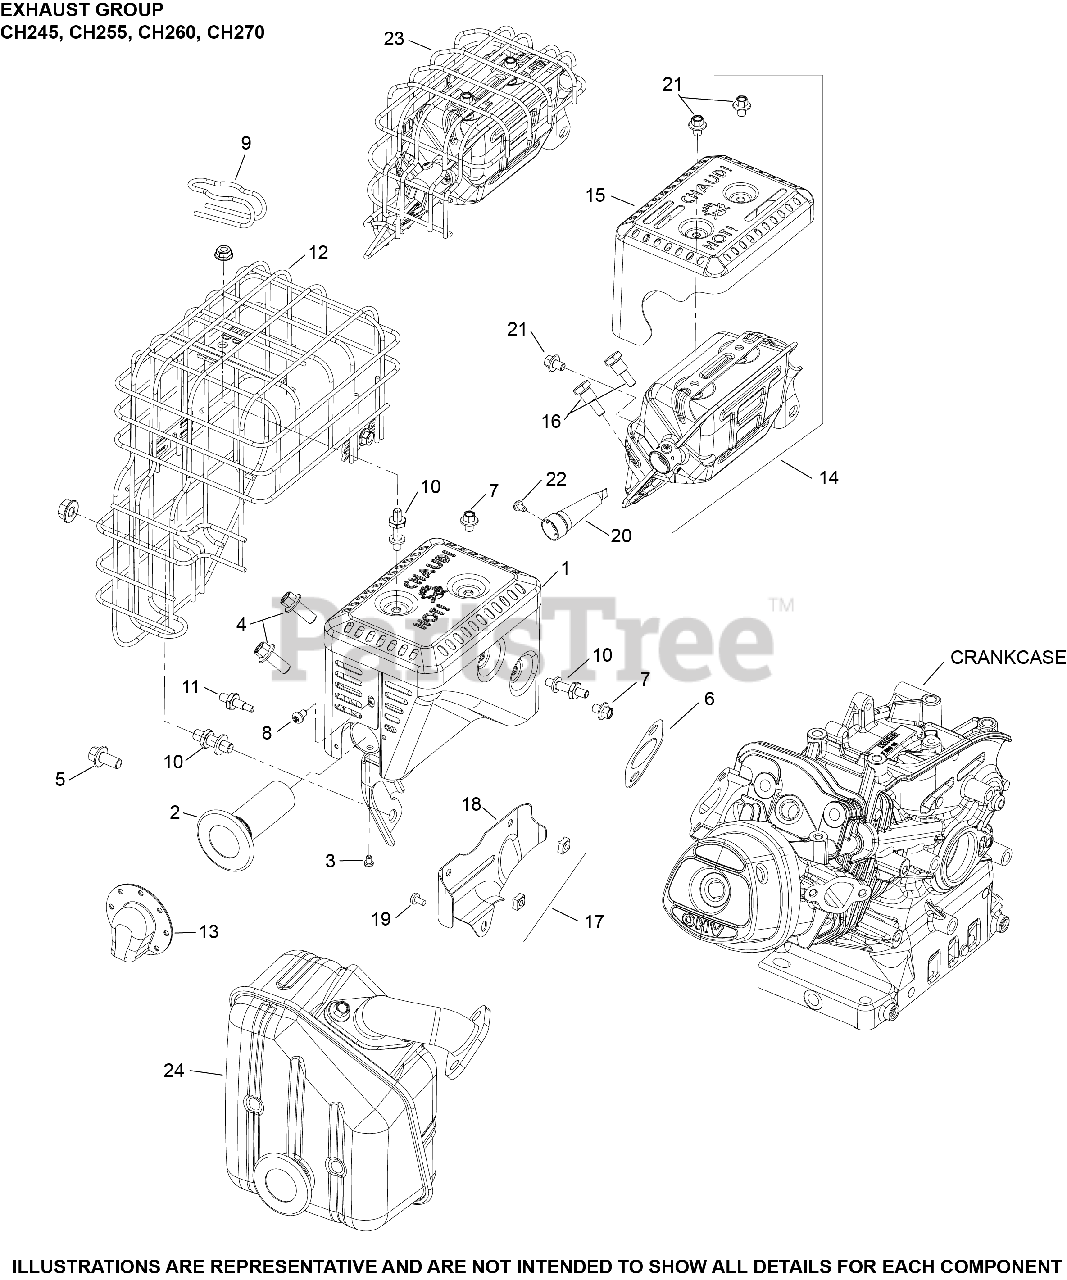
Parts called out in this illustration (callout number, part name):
1	KIT, MUFFLER
2	ARRESTOR ASSEMBLY, SPARK
3	SCREW, SPARK ARRESTOR
4	SCREW, M8 X 20
5	SCREW, FLG 8X1.25X16
6	GASKET, MUFFLER
8	SCREW, M5 X 8 (CKY)
13	DEFLECTOR, MUFFLER ASSY
